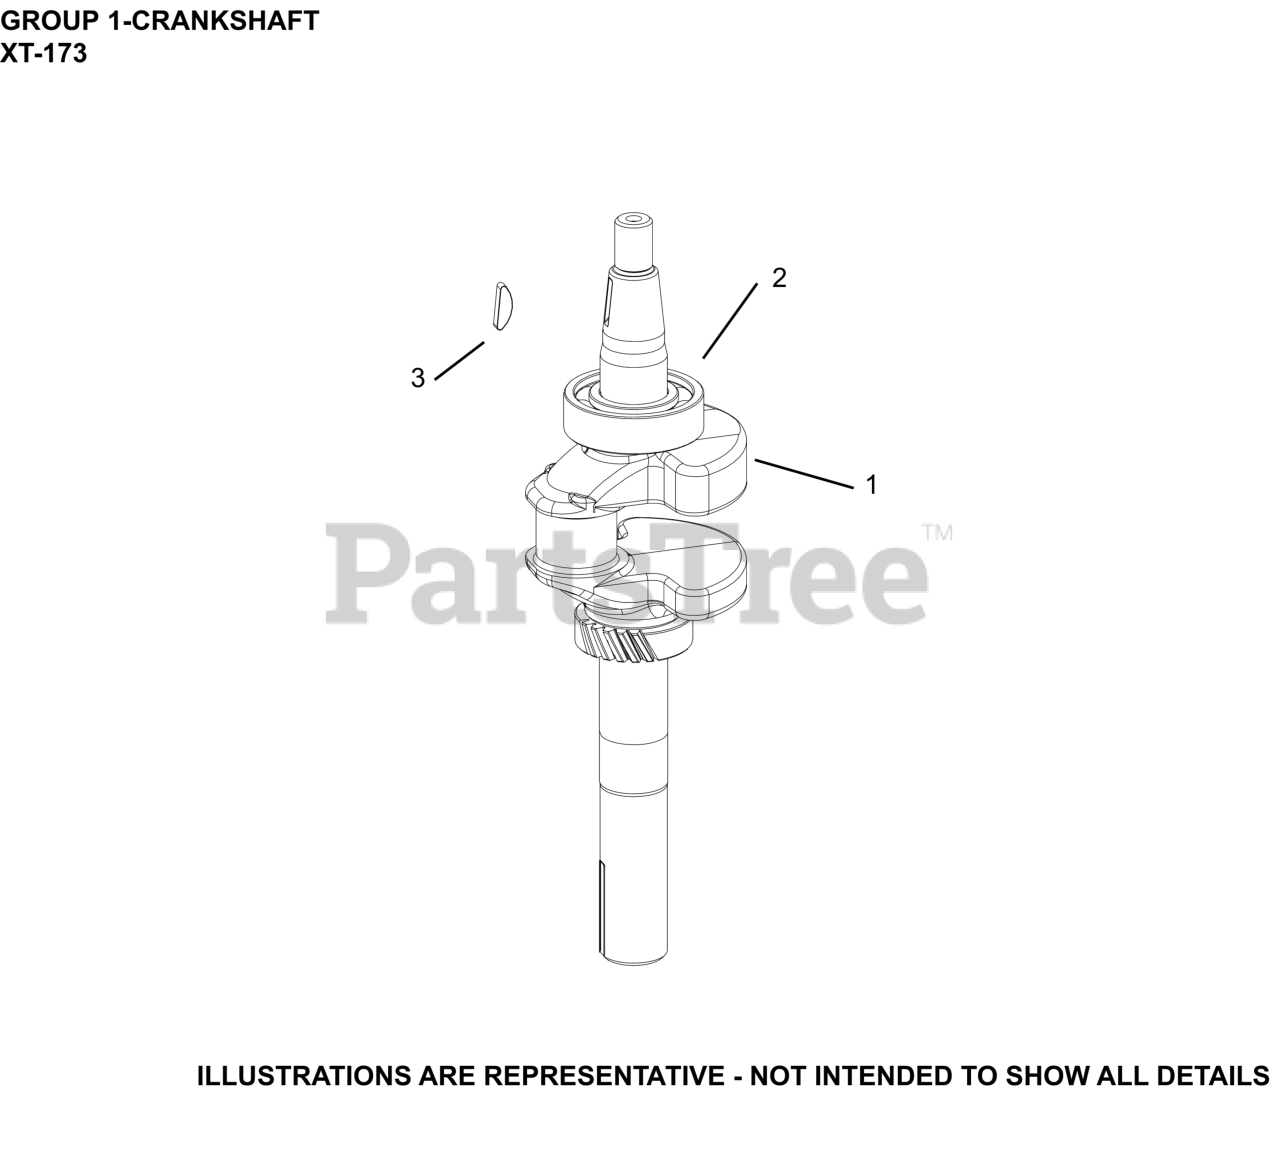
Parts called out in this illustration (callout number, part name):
1	CRANKSHAFT ASSEMBLY
2	BEARING, BALL
3	KEY, FLYWHEEL
